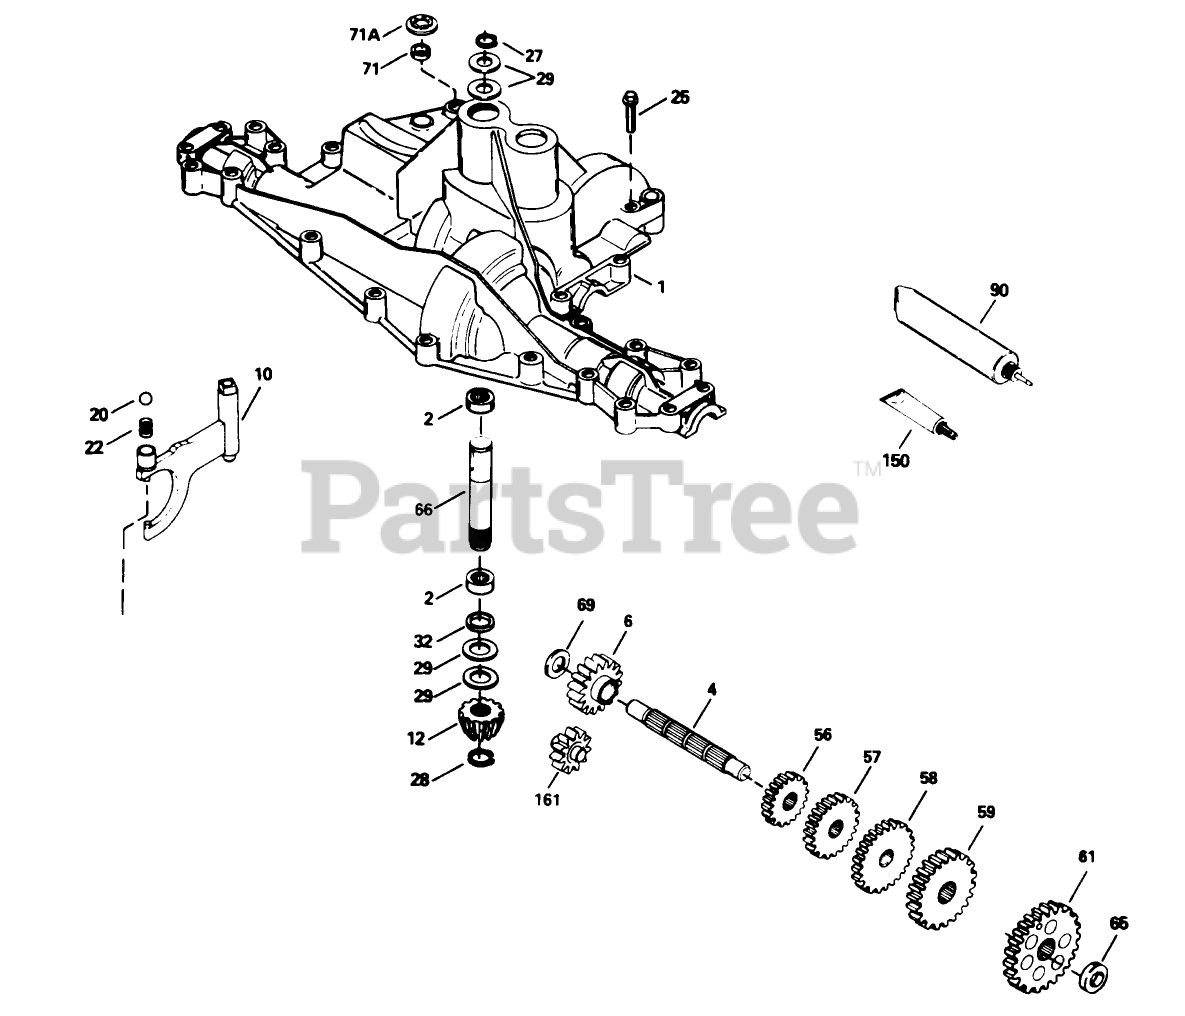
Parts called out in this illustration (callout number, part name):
1	Transaxle Cover
4	Countershaft
6	Spur Gear (16 Teeth)
10	Shift Rod Fork
12	Bevel Pinion (14 Teeth)
20	Ball (3/8" dia.)
22	Spring
25	Ring Set (.020 O S)
27	Ring-Snap
28	Ring-Retainer
29	Washer
32	O Ring
56	Gear-Spur, 15 Teeth
57	Gear-Spur 23 Teeth
58	Spur Gear (21 Teeth)
59	Gear-Spur (30 teeth)
61	Spur Gear (34Teeth)
65	Washer
66	Input Shaft (3.522" Ig.)
69	Thrust Washer
71	Cut Seal-Square
71A	Pushnut
90	Grease 32 Oz
150	Gasket Eliminator
161	Reverse Idler Assembly
